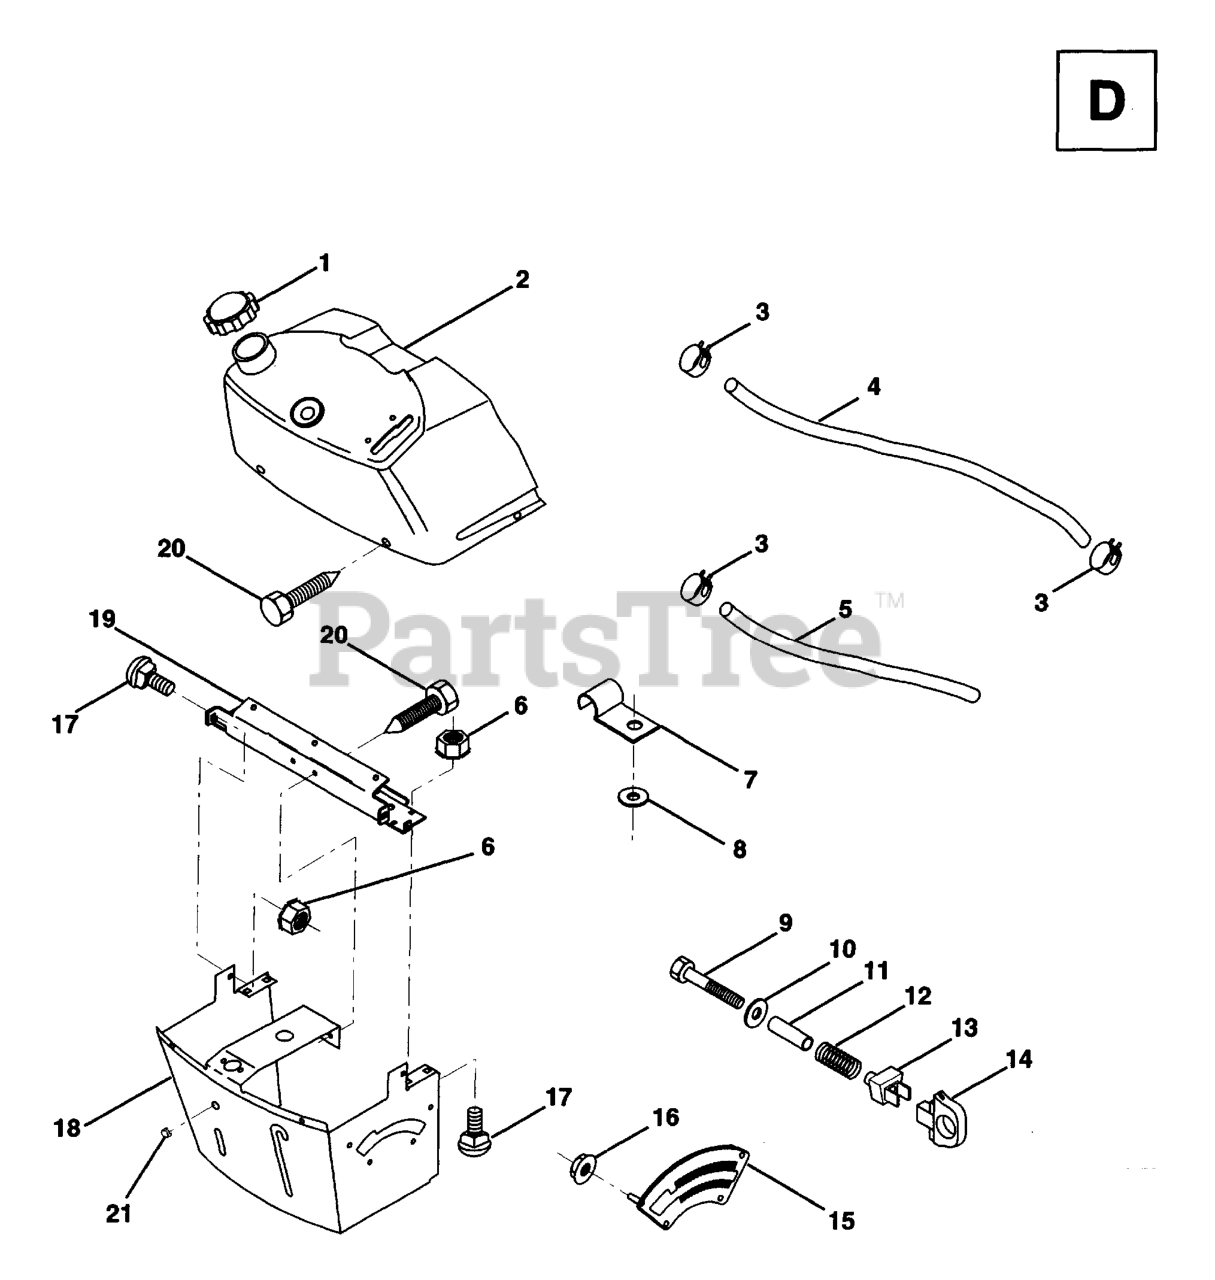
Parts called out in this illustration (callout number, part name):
1	CAP FUEL L.R. GREY
2	TANK ASM DASH LR
3	HOSE CLAMP
4	FUEL LINE
5	FUEL LINE T
6	NUT
7	CLIP T
9	BOLT HEX FIN 1/4-20X1 3/4
10	WASHER
11	SPACER SPLIT
12	SPRING.COMPRESSION
13	KNOB HGT RETAINER
15	ADJUSTER QUAD
16	NUT.PUSH.3/16
18	SUPT ASSY DASH
19	CROSS BRACE
20	Screw, Self-Tapping 1/4-20 x 1/2
